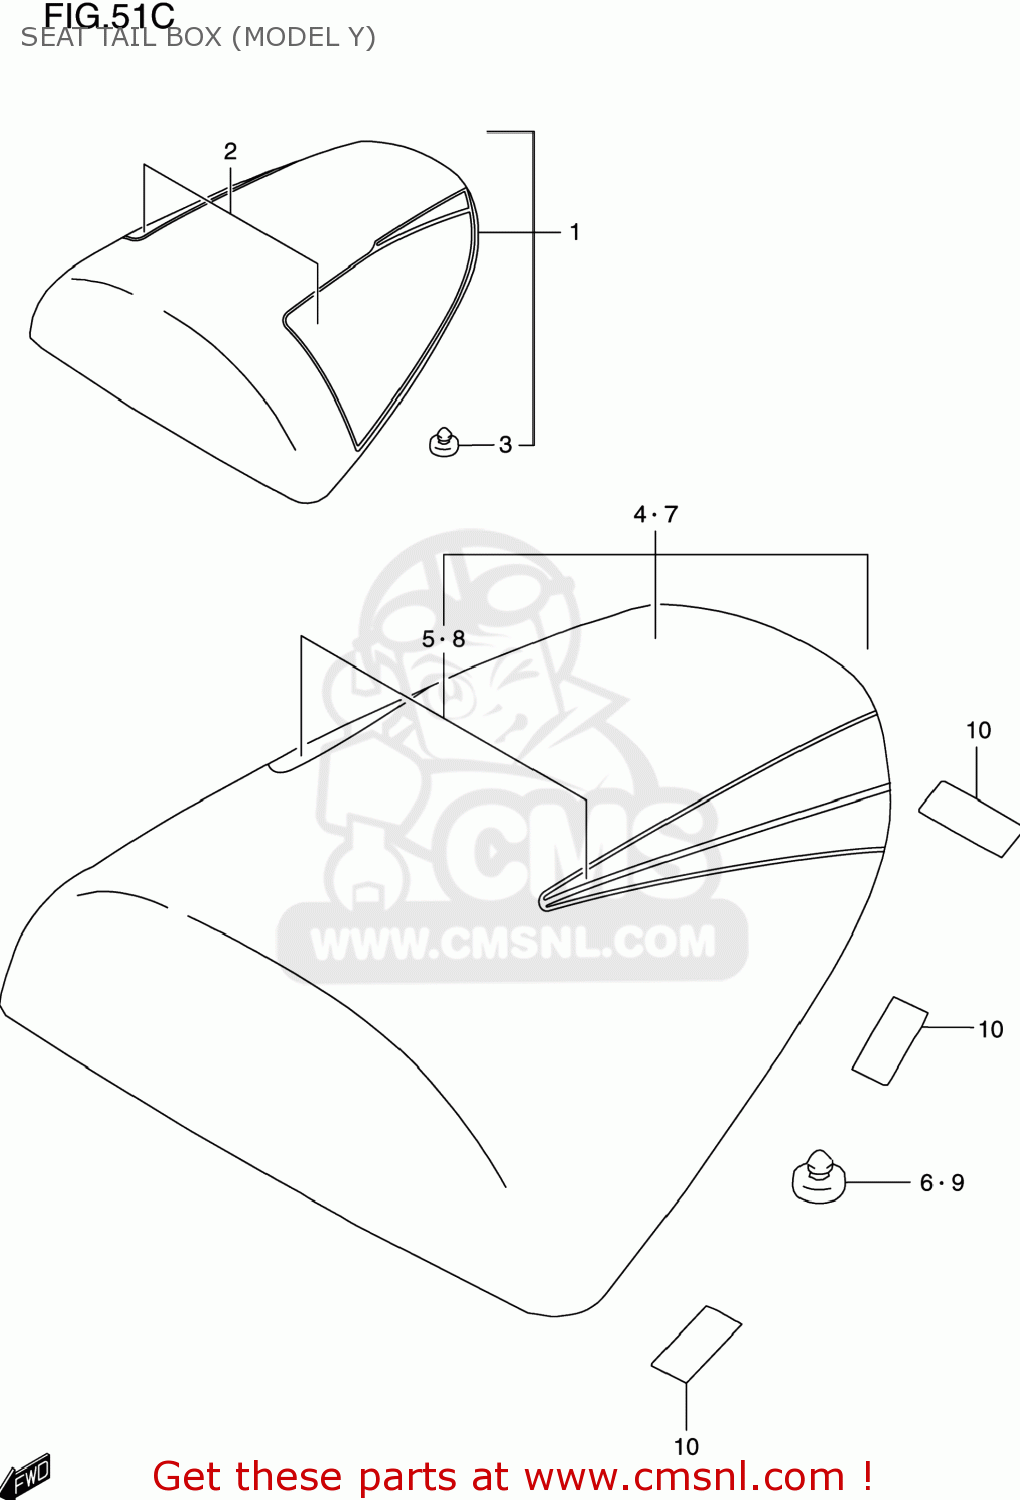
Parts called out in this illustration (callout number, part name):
1	BOX ASSEMBLY,SEAT TAIL
2	TAPE SET,BOX SEAT TAIL
3	CUSHION(11.5X22X20)
4	BOX ASSY,SEAT TAIL(BLACK)
5	TAPE SET,BOX SEAT TAIL
6	CUSHION(11.5X22X20)
7	BOX ASSEMBLY,SEAT TAIL (BLACK)
8	TAPE SET,SEAT TAIL
9	CUSHION(11.5X22X20)
10	PROTECTOR SET,SEAT TAIL BOX
